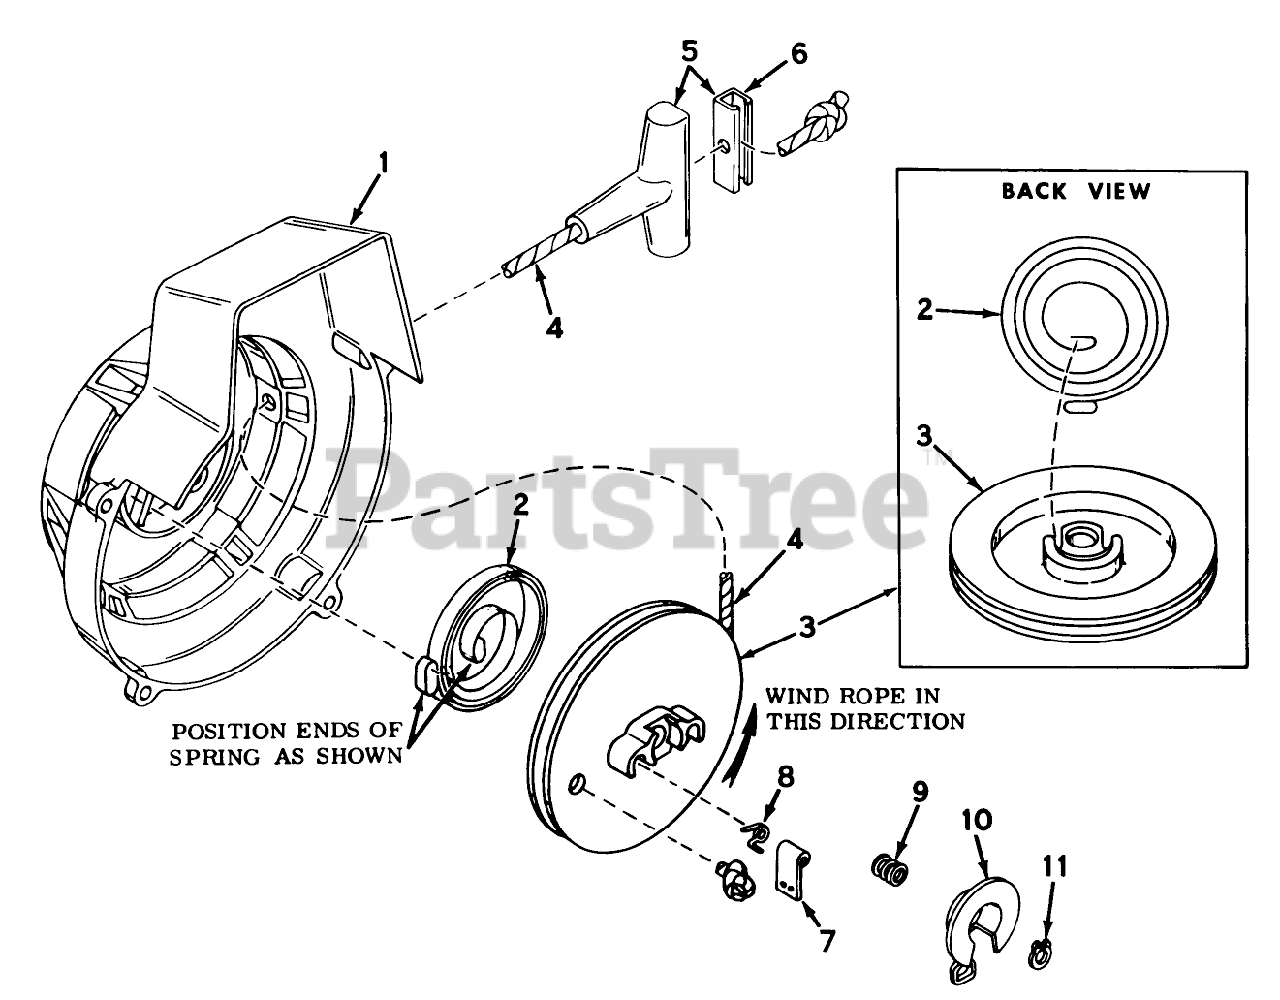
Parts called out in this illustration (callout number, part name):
1	Housing Assy., Shroud Starter
2	Spring, Rewind
3	Pulley, Starter Rope(Incl. No. 8)
4	Rope-Starter
5	Assy., Starter
6	Insert, Handle
7	Dog, Starter
8	Retum Spring, Left Hand Wound
9	Spring, Brake
10	Brake
11	E Ring Truarc
